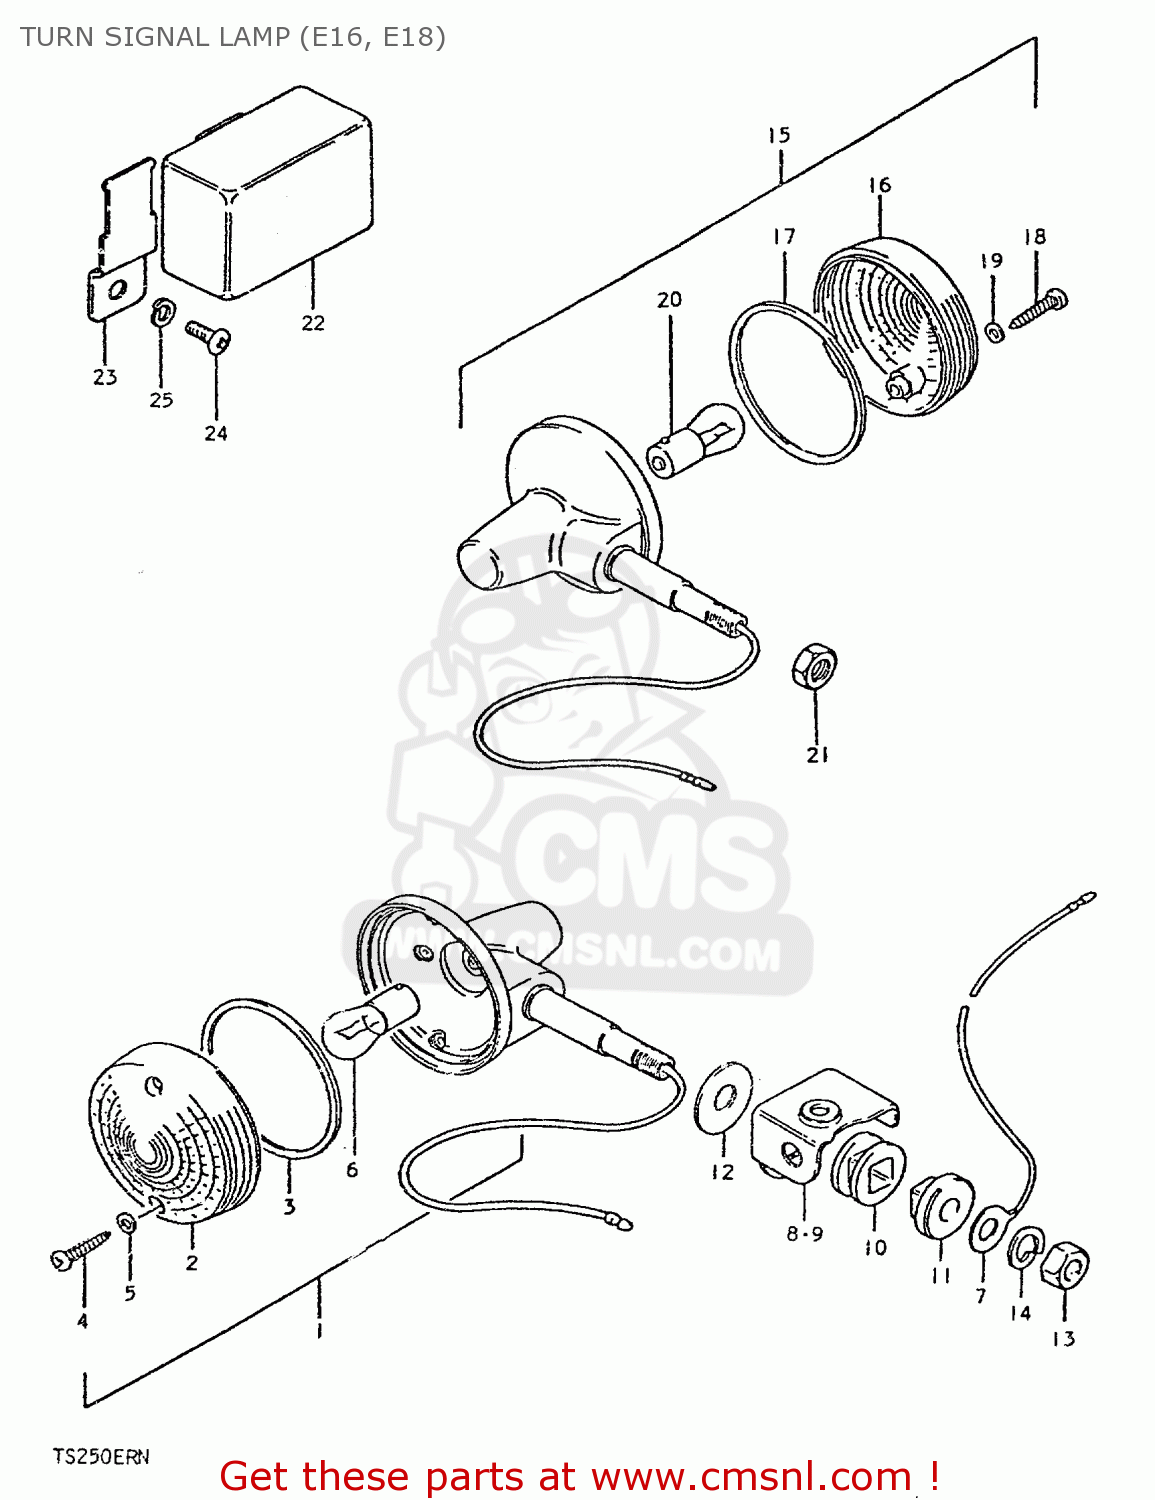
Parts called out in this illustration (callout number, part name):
1	LAMP, FRONT TURN SIGANL
2	LENS
3	GASKET (NAS)
4	SCREW
5	GASKET (NAS)
6	BULB (6V,21W)
7	LEAD WIRE,EARTH
8	BRACKET, FRONT TURN SIGNAL LAMP RH
9	BRACKET, FRONT TURN SIGNAL LAMP LH
10	CUSHION
11	SPACER,RR TURNSIGNAL LAMP
12	WASHER (10.5X30X2.3)
13	NUT
14	LOCK WASHER
15	LAMP, REAR TURN SIGNAL
16	LENS
17	GASKET (NAS)
18	SCREW
19	GASKET (NAS)
20	BULB (6V,21W)
21	NUT
22	RELAY, TURN SIGNAL
23	BRACKET,TURN SIGNAL RELAY
24	SCREW 6X12
25	LOCK WASHER
